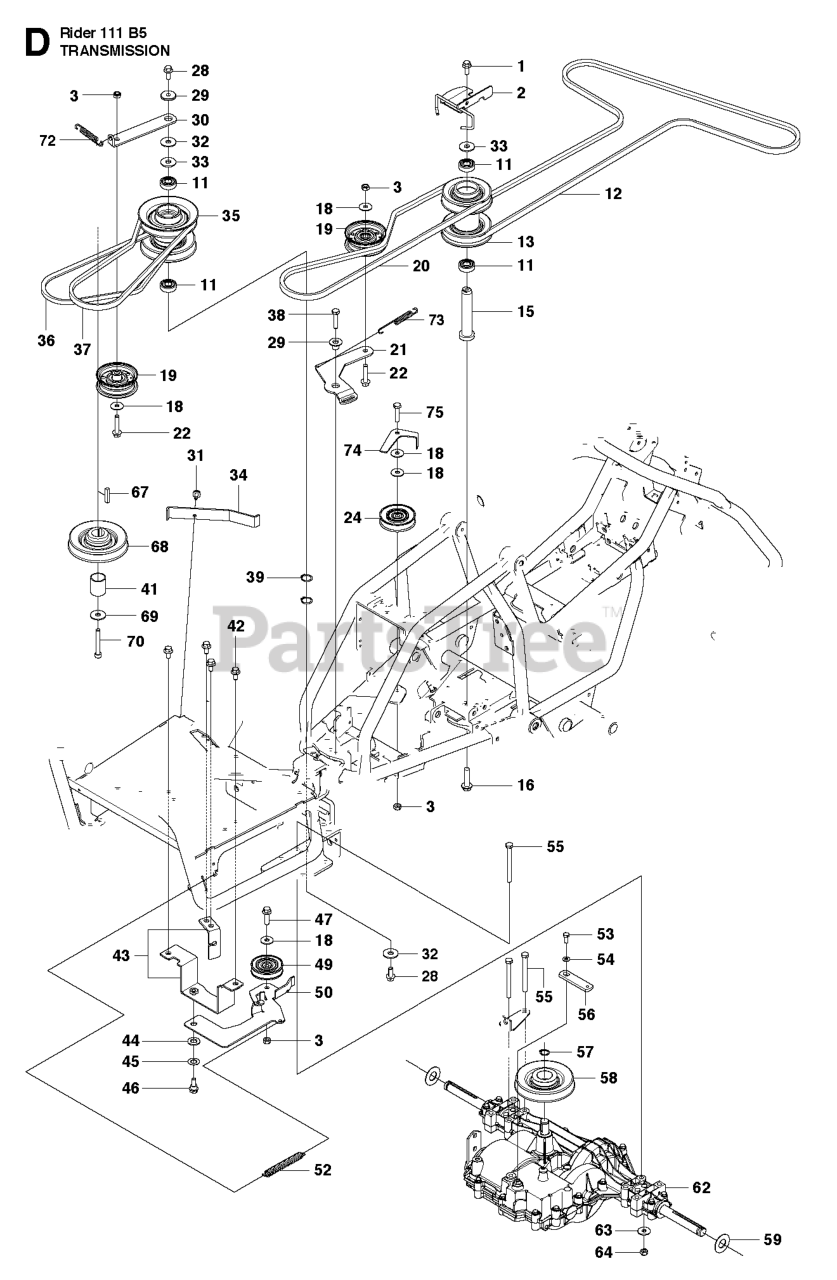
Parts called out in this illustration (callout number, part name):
3	LOCKNUT M8
11	BALL BEARING 6004-2RS1
19	IDLER PULLEY
21	BELT TENSIONER
28	BOLT
29	WASHER
38	BOLT
39	RETAINING RING SGA 20
44	WASHER - M12
45	SPRINGWASHER
47	SCREW
54	WASHER
57	Retaining Ring Sga 16
63	WASHER BRB 8.4X17
64	NUT
